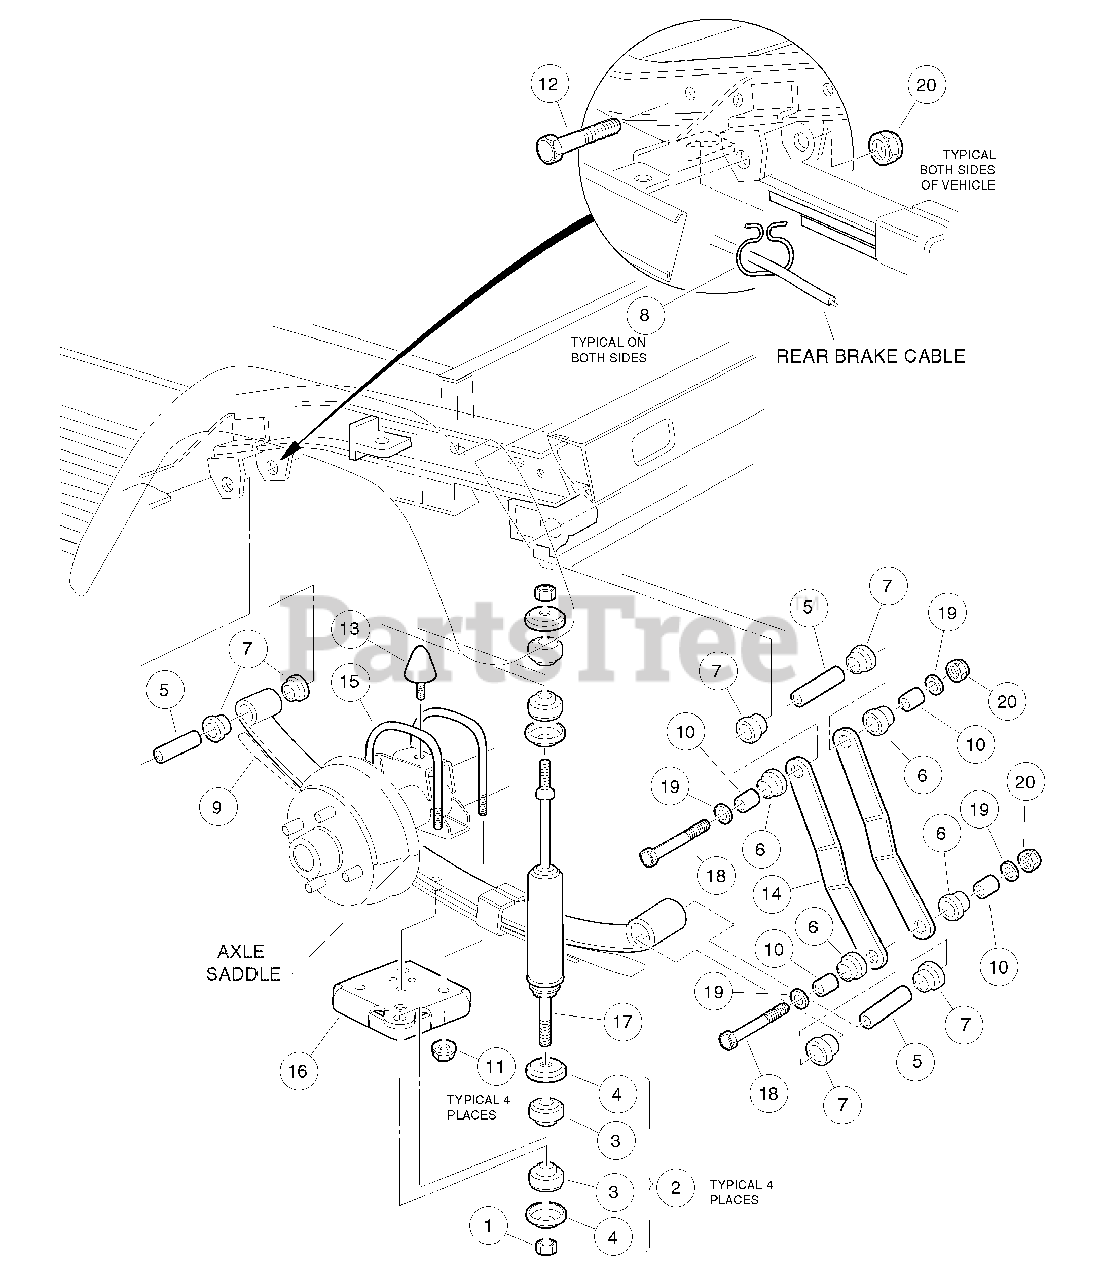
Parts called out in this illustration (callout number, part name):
1	Nut, 3/8-24 Hex
2	Kit, Shock Absorber Cushion
3	Cushion, Shock Absorber
4	Retainer, Shock Absorber Cushion
5	Bushing, Steel
6	Compression Mount
7	Bushing, Urethane
8	Hanger, Brake Cable
9	Spring, Rear Leaf
10	Spacer 0.38 ID X 0.500 OD
11	Locknut 7/16-14 Flange Dimple
12	Screw, 3/8-16 X 3.50 Hex Cap
13	Stud Mount
14	Shackle, Rear Spring -gas 272
16	Reinforced Spring Pad
17	Shock Absorber, Rear
18	Bolt, 3/8-16 X 4.50 Hex Head
19	Washer, 3/8 Type B Flat
20	Locknut, 3/8-16 Hex
